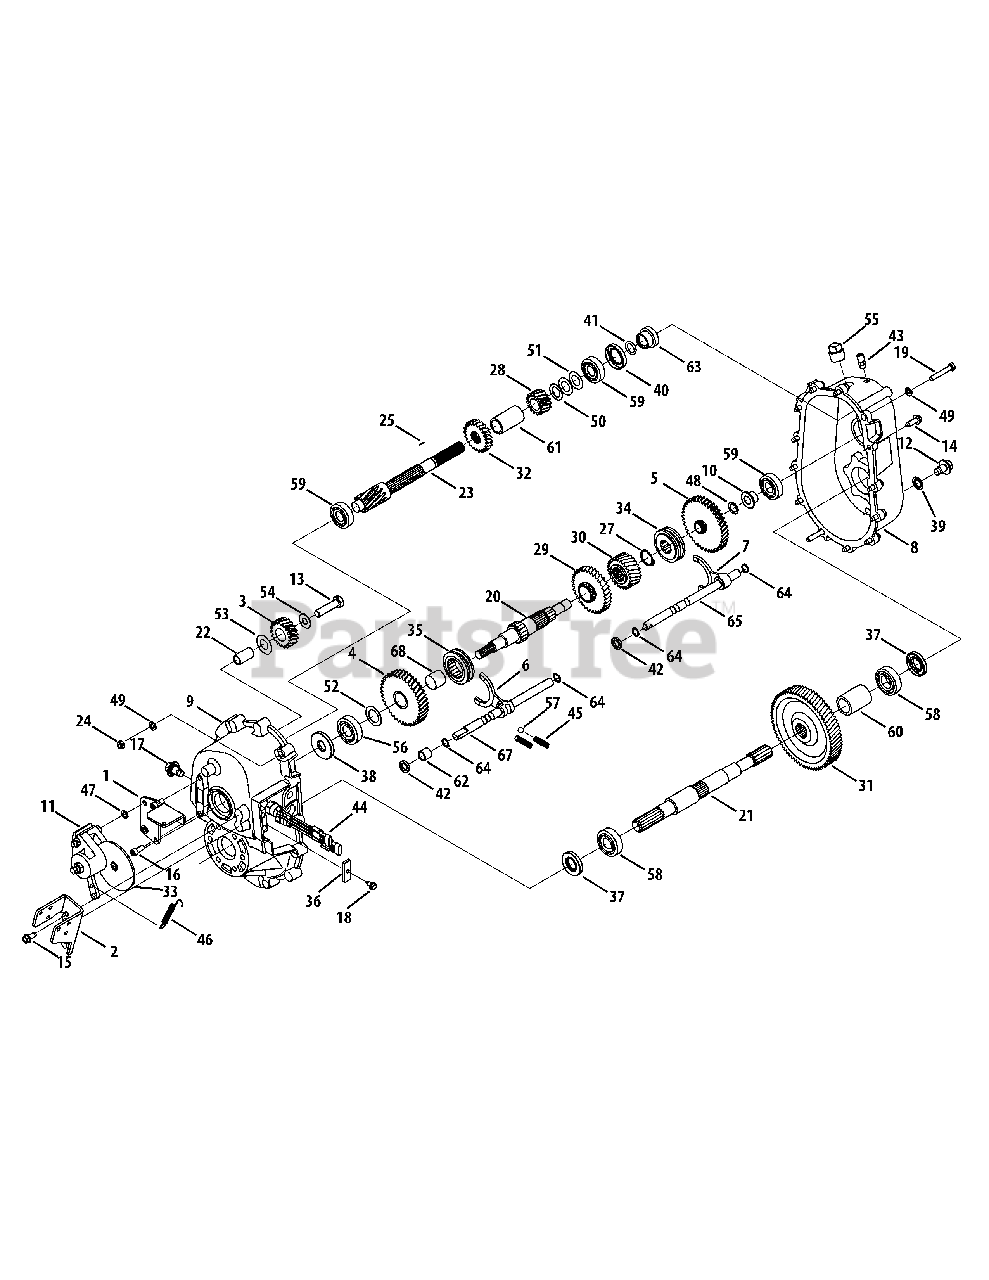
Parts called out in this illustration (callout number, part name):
1	Brkt Asm, Brk, Mnt, Painted
2	Brkt Asm, Shift, Trans, Painted
3	Gear Asm, Rev Idler
4	Gear, Rev, 39T
5	Gear Asm, Low Speed
6	Yoke, Actr, Uv
7	Yoke Actr, Lo
8	Hsg, Lh, Uv
9	Hsg, Rh, Uv
9	Bushing,Dowel
10	Spcr, Flg, .630 x .787 x .662
11	Brake Asm, Transfer Case
12	Scr, Plug, M14x1.5, Magnetic
13	Hhcs, 1/2-13, 2.00, Gr5, Lock
14	Scr, Tt, 5/16-18, 1.000, Hxindwsh
15	Scr, Tt, 5/16-18, 0.750, Hxindwsh
16	Scr, Soc Hd, 5/16-18, .750
17	Scr, Plug, M14x1.5 X .827
18	Scr, Tt, 1/4-20x.625, Hxindwsh
19	Hhcs, 5/16-18, 2.00, Gr5, Std
20	Shf, Mid, Transfer Case
21	Shf, Output, Transfer Case
22	Shf, Rev Idler
23	Shf, Input, Transfer Case
24	Nut, Hexlk, 5/16-18, Gra, Ctrlk
25	Pin, Roll, 1/8 Od, .63
26	Ext Snap Ring .625 Dia Shaft
27	Ring, Ret, 1.125 Dia Shaft
28	Gear, Low Pinion, 15t
29	Gear, High, 33t
30	Gear, Final Pinion, 22t
31	Gear, Final, 73t
32	Gear, Pnion, High, 22t
33	Disc, Brk, Uv
34	Colr, Lo
35	Colr, Hi-rev, 4x4
36	Plt, Detent Spring
37	Seal, Oil, 25x46x7
38	Seal, Oil, 20x52x7
39	Gskt, 14.15 X 24.6 X 1.5
40	Seal, Oil, 30 X 47 X 7
41	O-rg, .734 Id X .139
42	Seal, Oil, .563 X .875 X .188
43	Creeper Drive Housing Breather
44	Sw, Saf, Neut
45	Spr, 3/8 Od X 1 1/4 Lg
46	Spr, Extn, .38 Od X 3.9 Lg
47	Wash, Flat, .385 X .620 X .033
48	Wash, Flat, .635x.930x.033, Ht
49	Wash, Flat, .330 X .630 X .0635
50	Wash, Flat, .793 X 1.24 X .06, Ht
51	Wash, Flat, .793x1.368x.010, Ht
52	Wash, Flat, 1.007x1.542x.03, Ht
53	Wash, Thrust, .757 X 1.38 X .062
54	Wash, Flat, .51 X 1.12 X .06, Ht
55	Plug, Pipe, 3/4 Nptf
56	Brg, Ball, .79 Id X 2.05 Od X .6
57	Ball, Detent, .375
58	Brg, Ball, 25x52x15, 6205, Open
59	Brg, Ball, 20x47x14, 6204, Open
60	Spcr, Output Shaft
61	Spcr, Mid Shaft
61	Spcr, .930 x 1.125 x 3.019
62	Spcr, .566 X .725 X .650
63	Spcr, Input, Uv, Transfer Case
64	Ring, Ret
65	Shf, Actr, Lo
67	Shf, Actr, Fwd, Rev
68	Brg, Slv, 25mm x 28mm x 25mm
